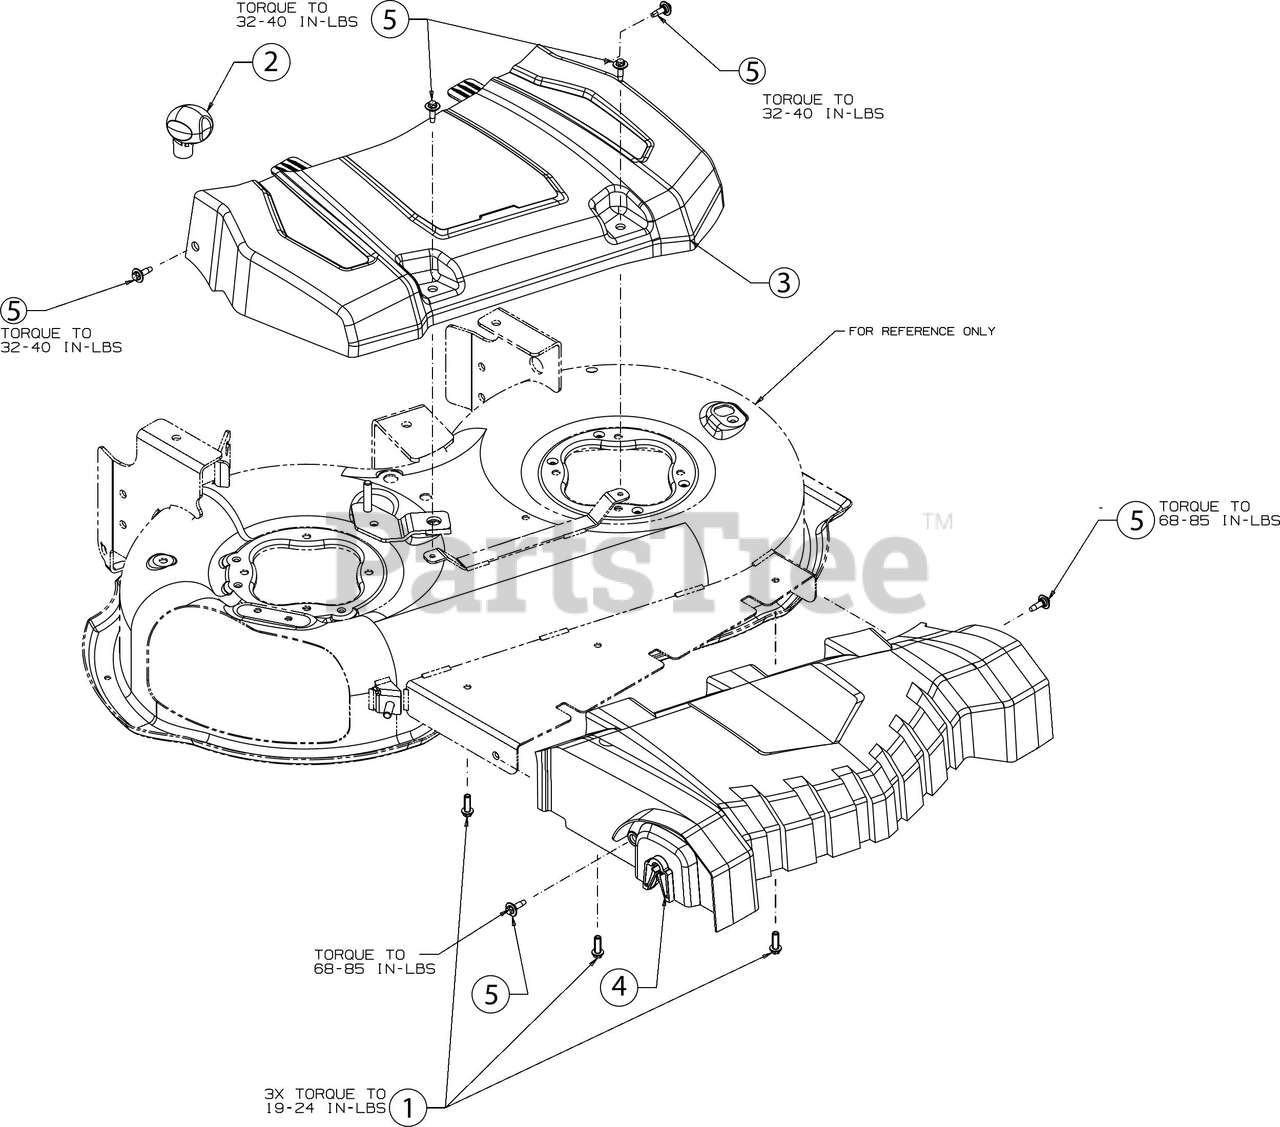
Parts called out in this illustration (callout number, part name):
1	SCREW 1/4 x .750
2	HEIGHT ADJUSTMENT KNOB-RED
3	28" BELT COVER
4	28" FRONT AXLE COVER
5	SHOULDER SCREW M6-1 .368 X.115
